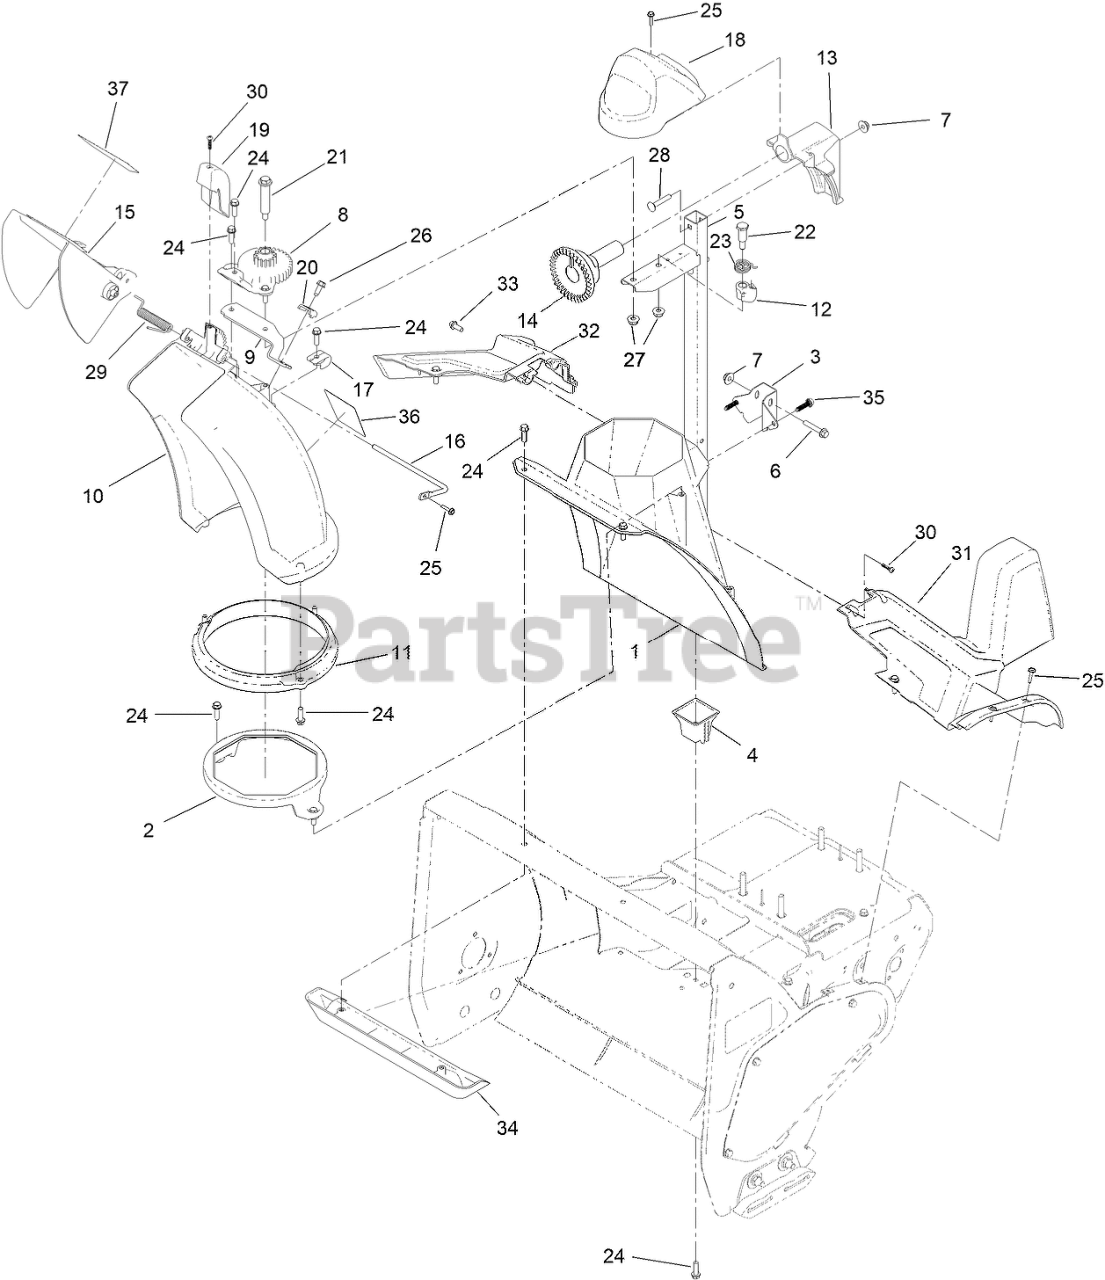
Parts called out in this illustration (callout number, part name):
1	CHUTE-LOWER
1	CHUTE-DISCHARGE
2	GUIDE-CHUTE
3	BRACKET-POST, SUPPORT (CHUTE)
4	RETAINER- POST, CHUTE
5	POST-CHUTE
6	SCREW-HHF
7	NUT-HF
8	GEAR-CHUTE
9	BRACKET-CABLE
10	CHUTE-DISCHARGE
11	RING-CHUTE
12	LATCH-CHUTE
13	MOUNT-GEAR, CHUTE
14	GEAR-FACE
15	DEFLECTOR-CHUTE
16	ROD-DEFLECTOR
17	GUIDE-CABLE
18	COVER-GEAR, CHUTE
19	CHUTE-COVER
20	CLAMP-CABLE
21	BOLT-SHOULDER
22	SCREW-SHOULDER, HH
23	SPRING-TORSION, LATCH (CHUTE)
24	SCREW-PLASTITE, HWH
25	SCREW-PLASTITE, HWH
26	SCREW-HWH
27	NUT-HF
28	BOLT-CARR
29	SPRING-TORSION
30	SCREW-PPH
31	SHROUD-UPPER, LH
32	SHROUD-LOWER, RH
33	SCREW-HWH
34	KICKER-HOUSING
35	SCREW-FLANGE, PLASTIC
36	DECAL - DANGER
37	DECAL-DANGER
